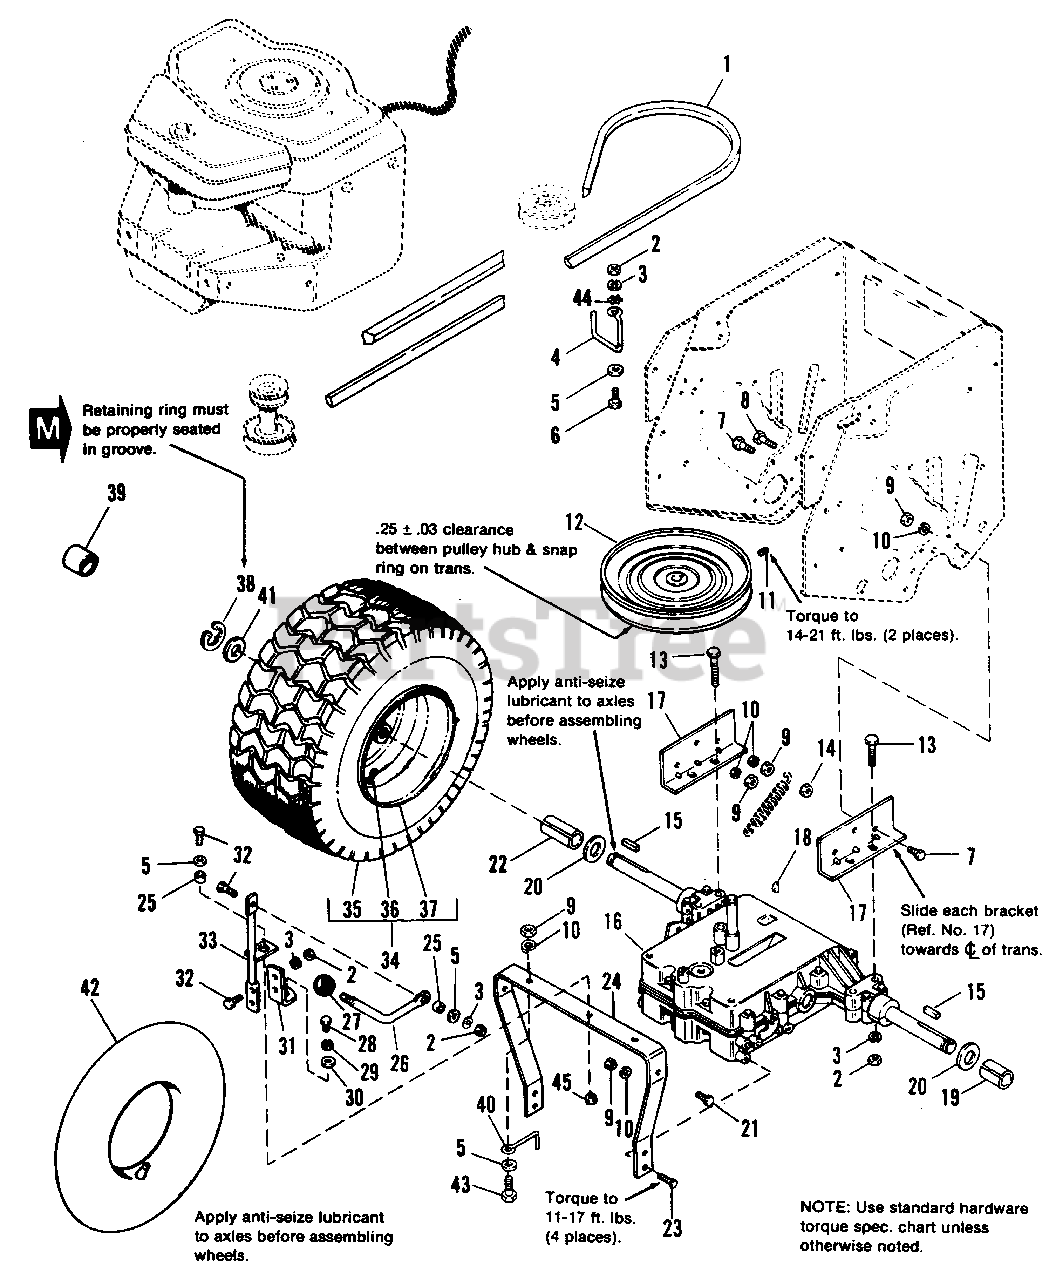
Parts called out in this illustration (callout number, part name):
1	V-BELT, Transmission Drive
2	NUT, Hex, Full, 5/16-18
3	LOCKWASHER, 5/16
5	WASHER, Plain, 5/16
6	CAPSCREW, Hex Hd., 5/16-18 x 1
7	CAPSCREW, Hex Hd., 3/8-16 x 3/4
8	CAPSCREW, Hex Hd., 3/8-16 x 1-1/4
9	NUT, Hex, Full, 3/8-16
10	LOCKWASHER, 3/8
11	SETSCREW, 5/16-18 x 5/8
12	PULLEY ASSY., Transmission
13	CAPSCREW, Hex Hd., 5/16-18 x 2-1/2
14	LOCKNUT, Hex, 3/8-16
15	KEY, 3/16 x 3/16 x 1-1/2
16	TRANSAXLE, 5 Speed
17	SUPPORT, Transmission, Rear
18	KEY, Woodruff, #9
20	WASHER
21	CAPSCREW, Hex Hd., 3/8-16 x 7/8
23	SCREW, Hex, Taptite, 5/16-18 x 5/8
24	SUPPORT, Transmission, Front
27	KNOB, Shift
28	CAPSCREW, Hex Hd., 1/4-28 x 5/8
29	LOCKWASHER, 1/4
30	WASHER, Plain, 3/16
31	LINK, Shift, Lower
32	CAPSCREW, Hex Hd., 5/16-18 x 7/8
33	SHIFT LINK ASSY., Upper
34	WHEEL & TIRE ASSY.
35	TIRE, 20 x 8-10
36	VALVE STEM & CAP
39	HUB CAP, Threaded
42	TUBE, 20 x 8-10
43	CAPSCREW, Hex, 3/8-16 x 1
44	LOCKWASHER, Ext. Tooth
45	NUT, Hex, Lock, 5/16-18
